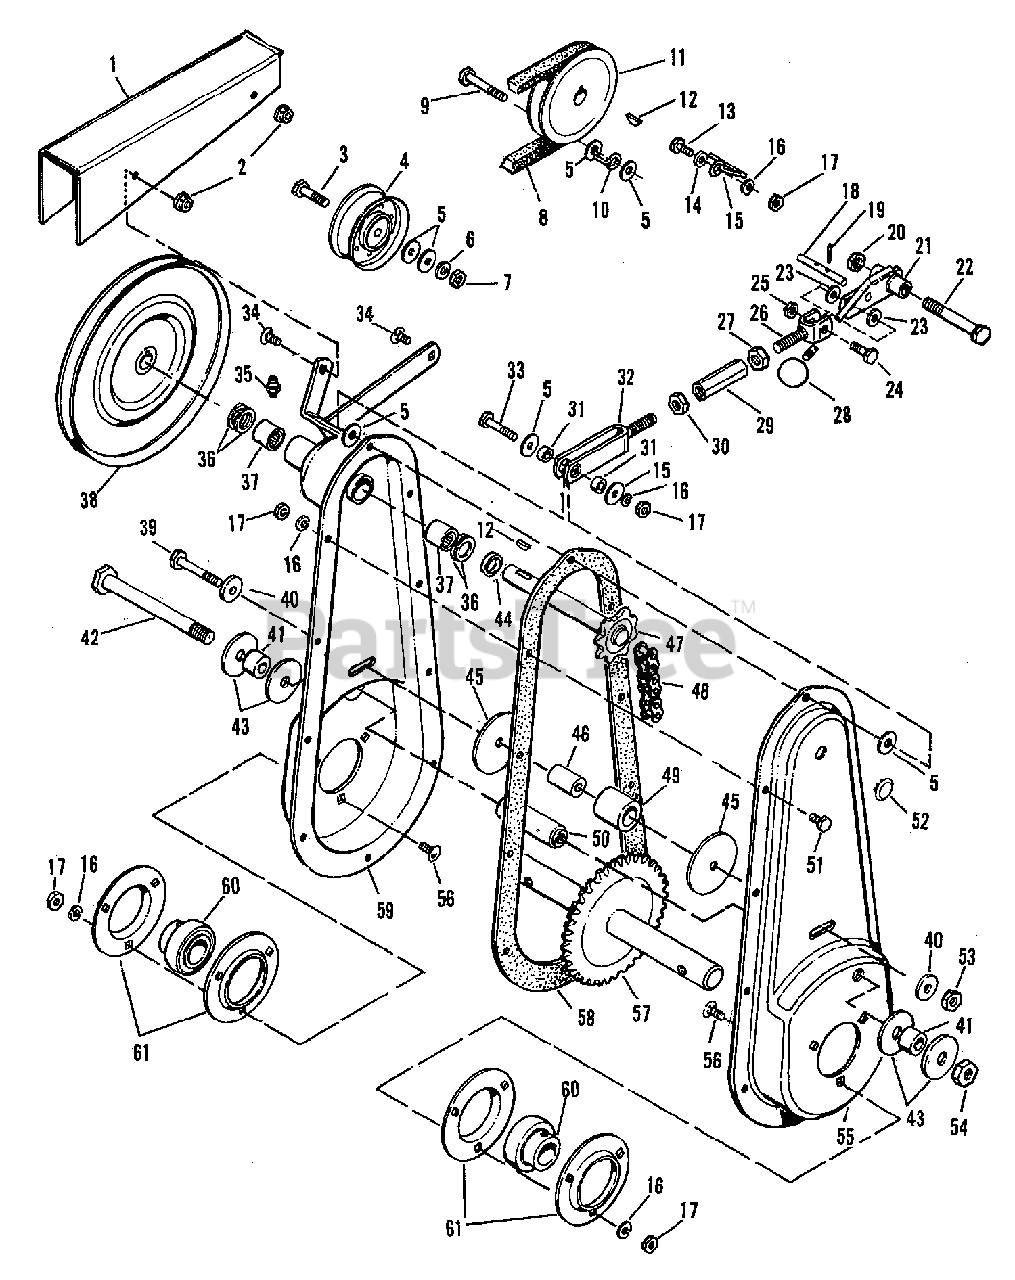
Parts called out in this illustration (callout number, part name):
2	NUT, Whiz Lock, 5/16-18
3	SCRWE, hex, 3/8-16 x 1-1/4
4	IDLER PULLEY
5	WASHER, Flat, 5/16
6	WASHER, Lock, 3/8
7	NUT, Hex, 3/8-16
9	SCREW, Hex Head, 3/8-16 x 1-3/4
11	PULLEY, Drive
12	KEY, Woodruff, 3/16-3/4
13	SCREW, Hex, Head, 5/16-18 x 3/4
14	WASHER, Plain, 1/4"
16	WASHER, Lock, 5/16"
17	NUT, Lock, 5/16-18
19	PIN, Cotter, 3/32 x 3/4
20	NUT, Hex, Lock, 7/16-14
21	CLUTCH LEVER ASSEMBLY
22	SCREW, Hex Head, 7/16-14 x 2-3/4
24	SCREW, Hex Head, 5/16-18 x 1
25	NUT, Hex Lock, 5/16-18
26	CLEVIS ASSEMBLY, L.H.
27	NUT, Hex Lock, 7/16-14, L.H. Thread
30	NUT, Hex, Lock, 7/16-14
32	YOKE ASSEMBLY, R.H.
33	SCREW, Hex Head, 5/16-18 x 1-1/2
34	BOLT, Carriage, 5/16-18 x 3/4
35	FITTING, Grease
37	BEARING, Needle
38	PULLEY, Driven
39	SCREW, Hex Head, 3/8-16 x 2-1/4
42	SCREW, Hex Head, 1/2-13 x 5-1/2
47	DRIVE SHAFT ASSEMBLY
51	SCREW, Hex Head, 5/16-18 x 5/8
52	PLUG, Button
53	NUT, Hex, Lock, 3/8-16
54	NUT, Hex Lock, 1/2-13
55	CASE ASSEMBLY, R.H.
56	BOLT, Carriage, 5/16-18 x 3/4
57	TINE SHAFT ASSEMBLY
58	GASKET, Case
59	CASE ASSEMBLY, L.H.
61	BEARING FLANGE
